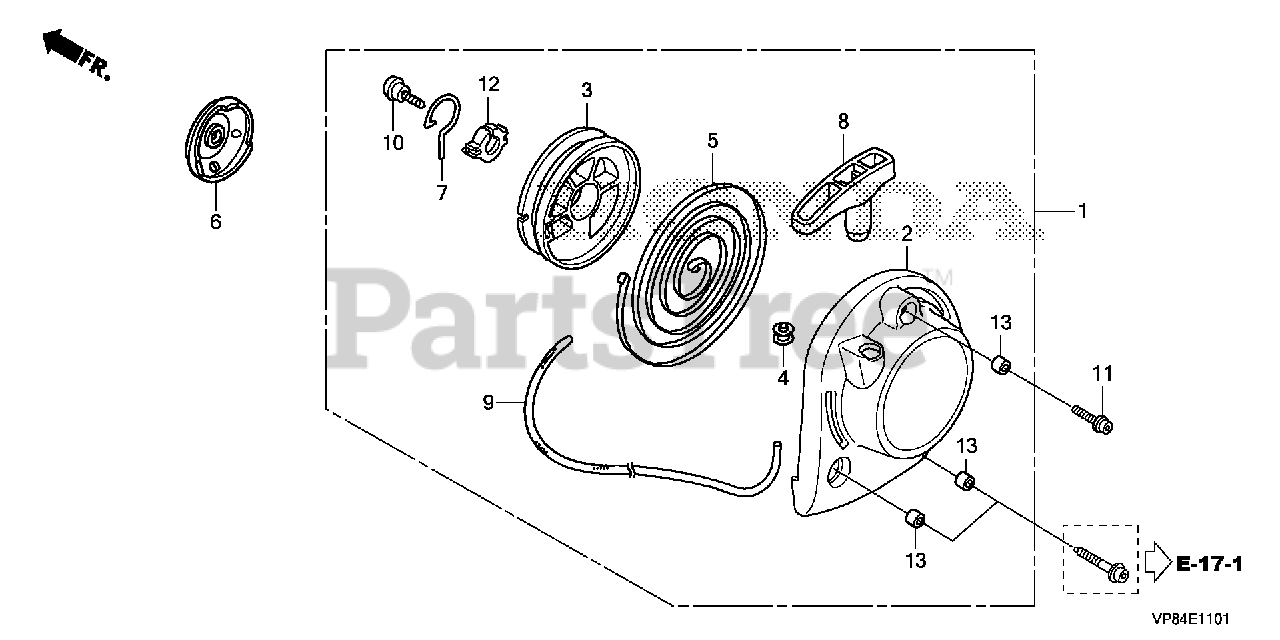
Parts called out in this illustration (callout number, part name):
1	STARTER ASSY., RECOIL
2	CASE, RECOIL STARTER
3	REEL, RECOIL STARTER
4	GUIDE, ROPE
5	SPRING, RECOIL STARTER
6	PULLEY, RECOIL STARTER
8	KNOB, RECOIL STARTER
9	ROPE, RECOIL STARTER (#3.5X40")
10	SCREW, SETTING
11	BOLT, SOCKET (5X16)
13	COLLAR A, HEAD COVER
